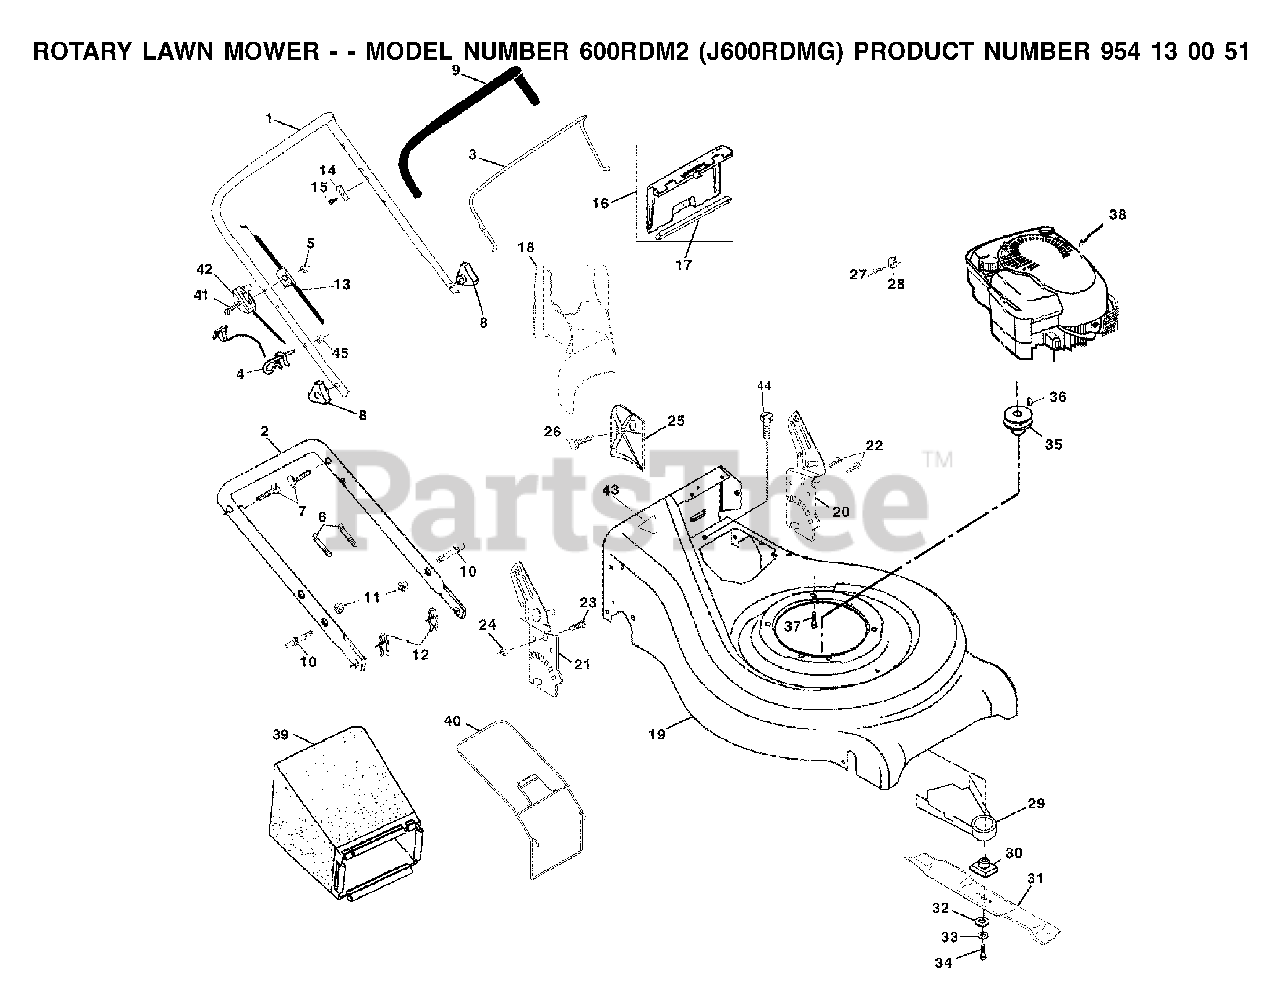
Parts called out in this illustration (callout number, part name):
2	HANDLE
3	CONTROL BAR
4	ROPE, GUIDE
5	NUT
6	TIE GUIDE
7	HANDLE BOLT
9	GRIP.HANDLE.FOAM
10	BOLT
11	NUT
12	HAIRPIN COTTER
13	ENGINE ZONE CONTROL
14	BRACKET UPSTOP
15	SCREW.HEX.HEAD.WASHER.10-16
16	REAR DOOR KIT
17	SEAL, DOOR
18	MULCHER PLUG
20	.RACKET
22	SELF-TAPPING SCREW 5/16-18X3/4
23	BOLT, HEX HEAD 5/16-18
25	CLIPPING DEFLECTOR
27	SCREW.HEX.HEAD.WASHER.10-16
28	CABLE CLAMP(ENGINE)
29	SHIELD.DEBRIS.21.RWGD.EZ
30	RP BLADE ADAPTOR
32	WASHER,HARDEN
33	LOCKWASHER
34	SCREW, HEX HD 3/8-24 X 1-3/8
35	ENGINE.PULLEY.FWG
36	HI PRO KEY PM
37	BOLT 3/8-16X1-1/8
40	FRAME.GRASS.CATCHER.21.RGD
41	SCREW 1/4-20 X 2.12
42	CONTRL.THROTTLE.
43	DECAL.INTERNATIONL.CUTFINGER
45	NUT
